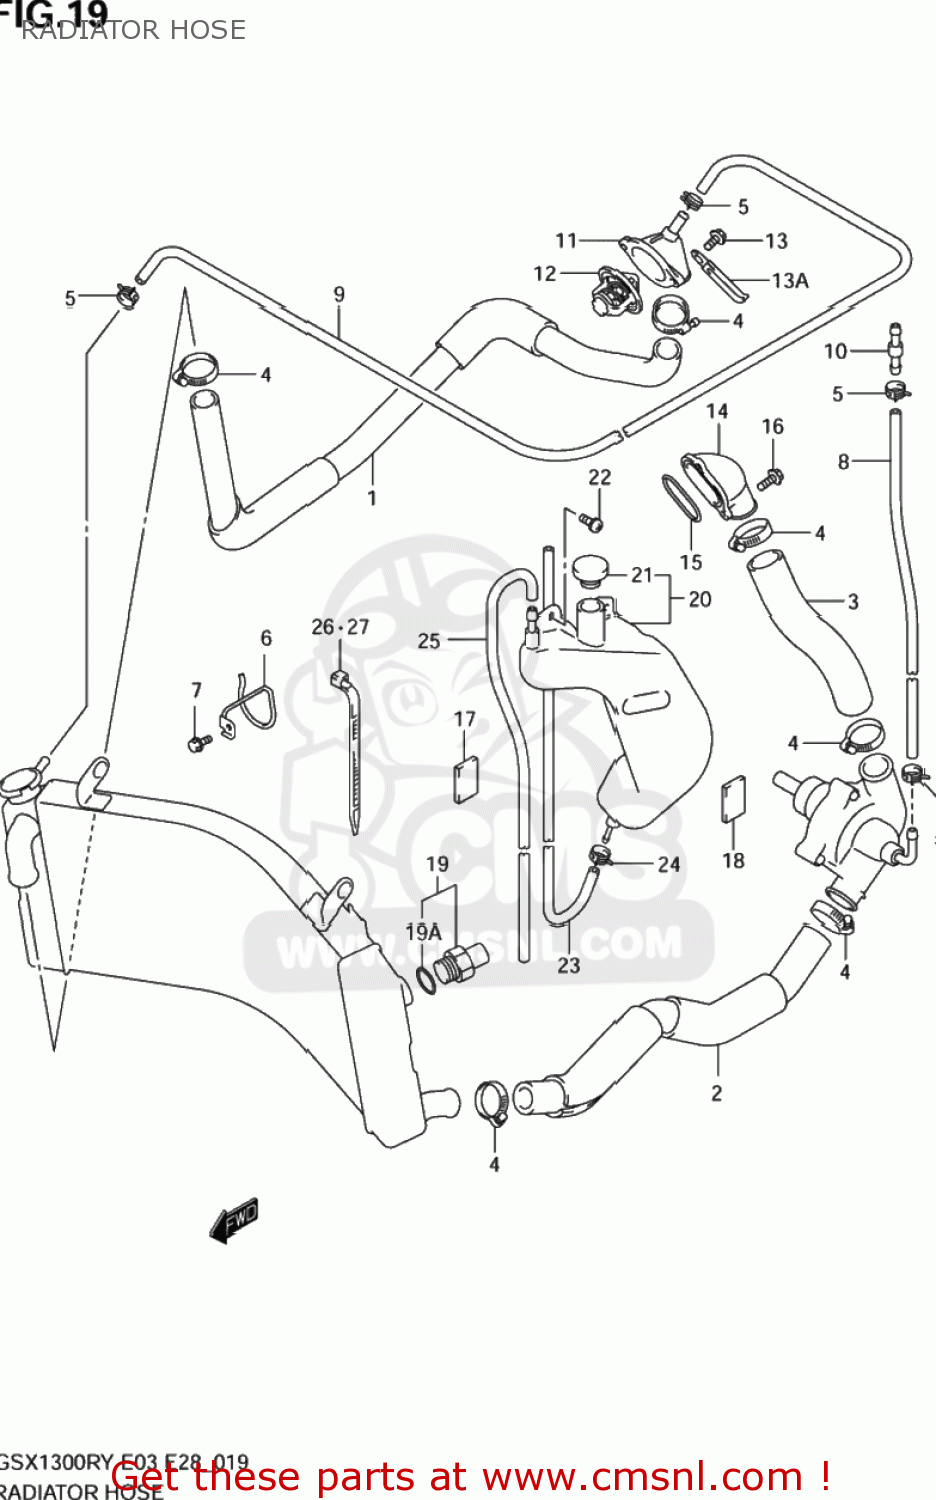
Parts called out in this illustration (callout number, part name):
1	HOSE,RADIATOR INLET
2	HOSE,RADIATOR OUTLET
3	HOSE,CYLINDERL INLET
4	CLAMP
5	CLAMP
6	CLAMP,RADIATOR INLET HOSE
7	BOLT
8	HOSE,WATER BYPASS NO.1
9	HOSE,WATER BYPASS NO.2
10	BOLT UNION
11	COVER,THERMOSTAT
12	THERMOSTAT,WATER 82 DEG
13	SCREW
13A	CLAMP(L:65)
14	CONNECTOR,CYL.
15	O RING,CYL WATER CONNECTOR
16	BOLT
17	CUSHION,HEADLAMP COVER
18	CUSHION,FR FENDER
19	SWITCH,RADIATOR FAN
19A	O-RING
20	TANK ASSY,RESERVOIR
21	CAP,RESERVOIR TANK
22	SCREW(6X20)
23	HOSE,RESERVOIR TANK
24	CLIP
25	HOSE,RESERVOIR TANK OUTLET
26	CLAMP(L:165)
27	CLAMP(L:165)
